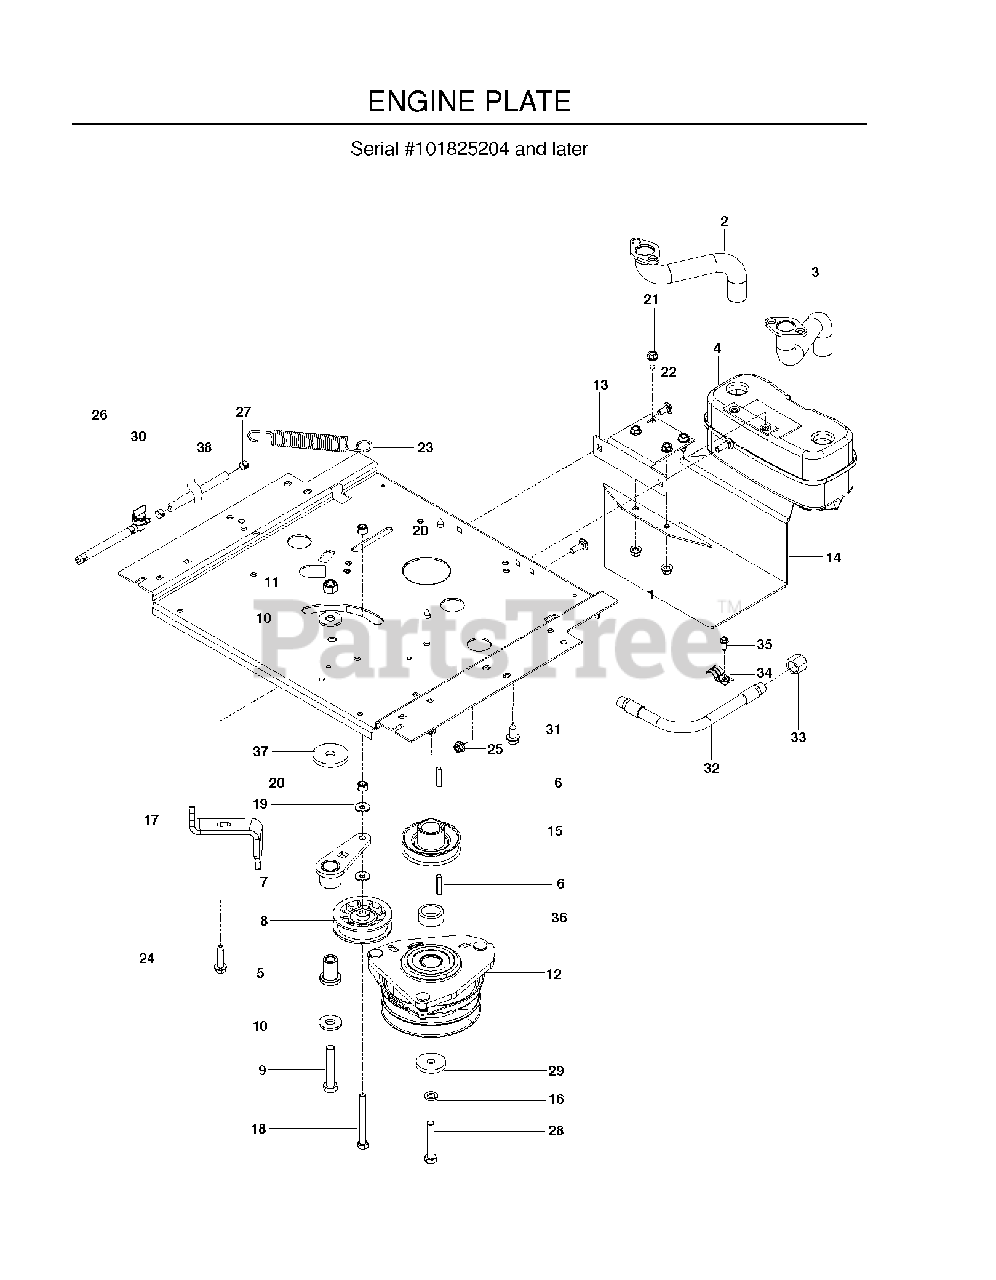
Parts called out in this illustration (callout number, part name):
1	PLATE, ENGINE WIDE, BLACK
2	RP.PIPE-EXHAUST LH
3	RP.PIPE-EXHAUST RH
4	MUFFLER ASM TWIN
5	PIVOT, IDLER
6	KEY, 1/4 SQ X 1 1/4
7	IDLER ARM WELDMENT
8	PULLEY, IDLER
9	HCS 1/2C X 2 3/4
10	WASH USS FLAT 1/2
11	NUT 1/2-13 HEX NYLOC ZD
12	CLUTCH ELECTRIC
13	BRACKET, MUFFLER, BLACK
14	GUARD, MUFFLER, BLACK
15	PULLEY, C'SHAFT, 3.57 OP
16	WASHER 7/16 LOCK
17	STOP, CLUTCH, BLK
18	HCS 3/8-16X3 1/2 GR5
19	WASHER 5/16 FLAT
20	NUT 3/8-16 NYLOC
21	BOLT 5/16-18 X 3/4
22	BOLT 5/16C X 3/4" CARRIAGE
23	SPRING, DECK DRIVE
24	BOLT 3/8-16 X 1 1/2 ZINC CLEAR
25	5/16-18 NYLOC FLANGE NUT
26	HOSE 1/4 X 8
27	HOSE CLAMP
28	BOLT 7/16F X 2 1/2
29	SPINDLE WASHER
30	FUEL VALVE
31	HHFS 3/8-16 X 1.0 THD FORMING
32	OIL DRAIN HOSE
33	DRAIN CAP
35	SCREW 1/4 X 5/8
36	SPACER, CLUTCH, 0.600
37	HEAVY WASHER
38	HOSE, FUEL .25 ID X 26"
